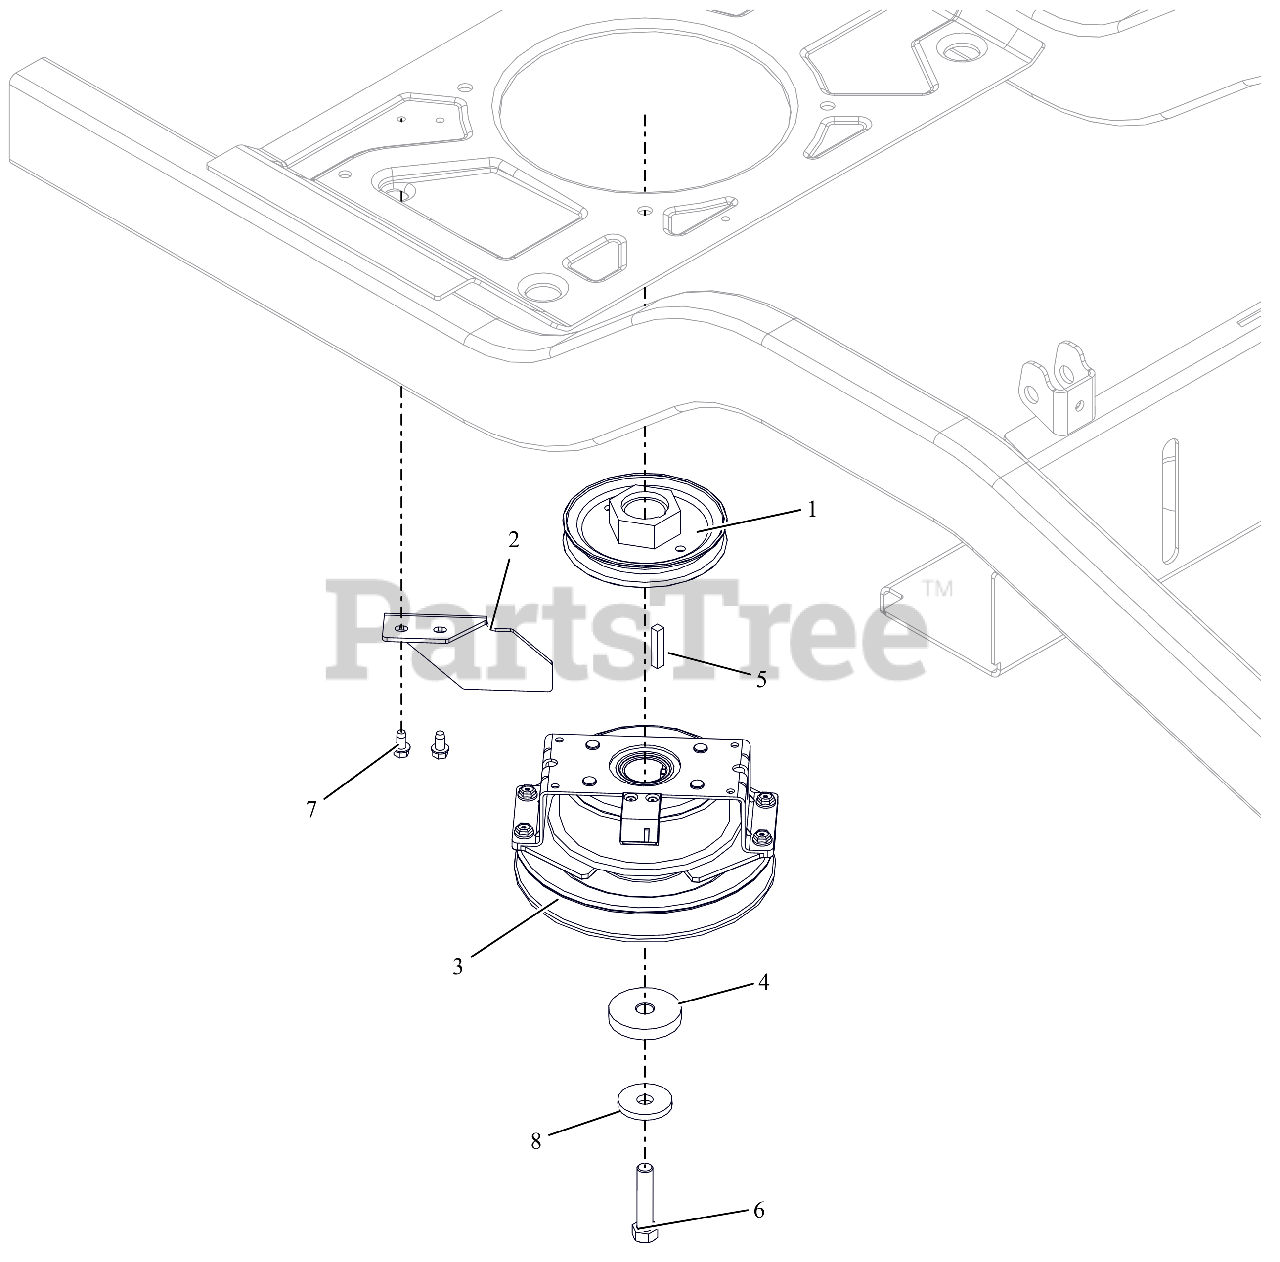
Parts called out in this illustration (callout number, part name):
1	WLDMT,PULLEY-4.50ODX1.127
2	BRKT, CLUTCH STOP HD
3	CLUTCH, OGURA DBLS SPRG 1.13"
4	SPACER, .474/.459X2.00X.350
5	KEY-SQ .25 X 1.25 X .25 SAE
6	BLT, HEX 0.4375-20X2 G8 ZCC NT
7	SCR-TAP .25-20X.50 HWH ZCC
8	WASHER, 7/16" SPRING DISK
